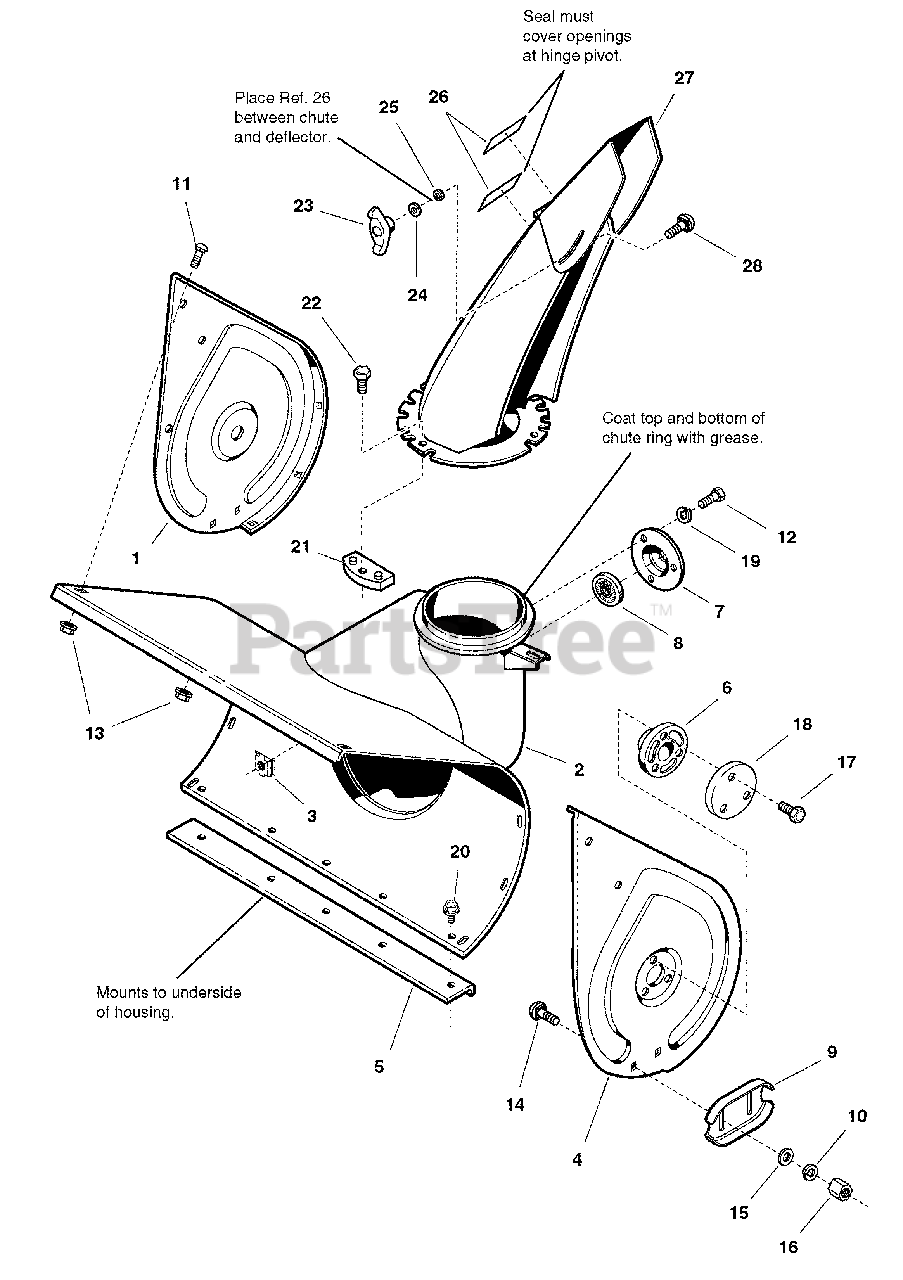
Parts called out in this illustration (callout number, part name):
1	END PLATE, RH- Auger Housing, Orange
2	AUGER HOUSING ASSEMBLY, 22" (Orange)
2	AUGER HOUSING ASSEMBLY, 24" (Orange)
3	RETAINER NUT, 5/16-18
4	END PLATE, LH- Auger Housing, Orange
5	BLADE, Scraper- 22 inch
5	BLADE, Scraper- 24 inch
6	BEARING, Auger
7	RETAINER, Bearing
8	BALL BEARING
9	SKID SHOE, Reversible, Orange
10	WASHER, 3/8 inch Split Lock
11	BOLT, 1/4-20 x 1/2 Short Square Neck Carriage, GR 5
12	SCREW, 5/16-18 x 5/8 Hex Head Cap, GR 5
13	NUT, 1/4-20 Hex Flange Lock Large
14	CARRIAGE BOLT, 3/8-16 x 3/4
15	WASHER, 3/8 Flat
16	NUT, 3/8-16 Hex Nyloc
17	SCREW, 5/16-18 x 1 Hex Washer Self-Tap
18	CAP, Bearing, Orange
19	WASHER, 5/16 Split Lock
20	SCREW, 1/4-20 x 3/8 Hex Washer Self-Tap
21	RETAINER, Spout
22	SCREW, #10-24 x 5/8 Hex Washer Self-Tap
23	KNOB, Wing 5/16-18
24	WASHER, .34 x .69 x .08 Flat
25	WASHER, Nylon
26	DECAL, Hinge, Orange
27	CHUTE, Discharge
28	CARRIAGE BOLT, 5/16-18 x 3/4, GR5
